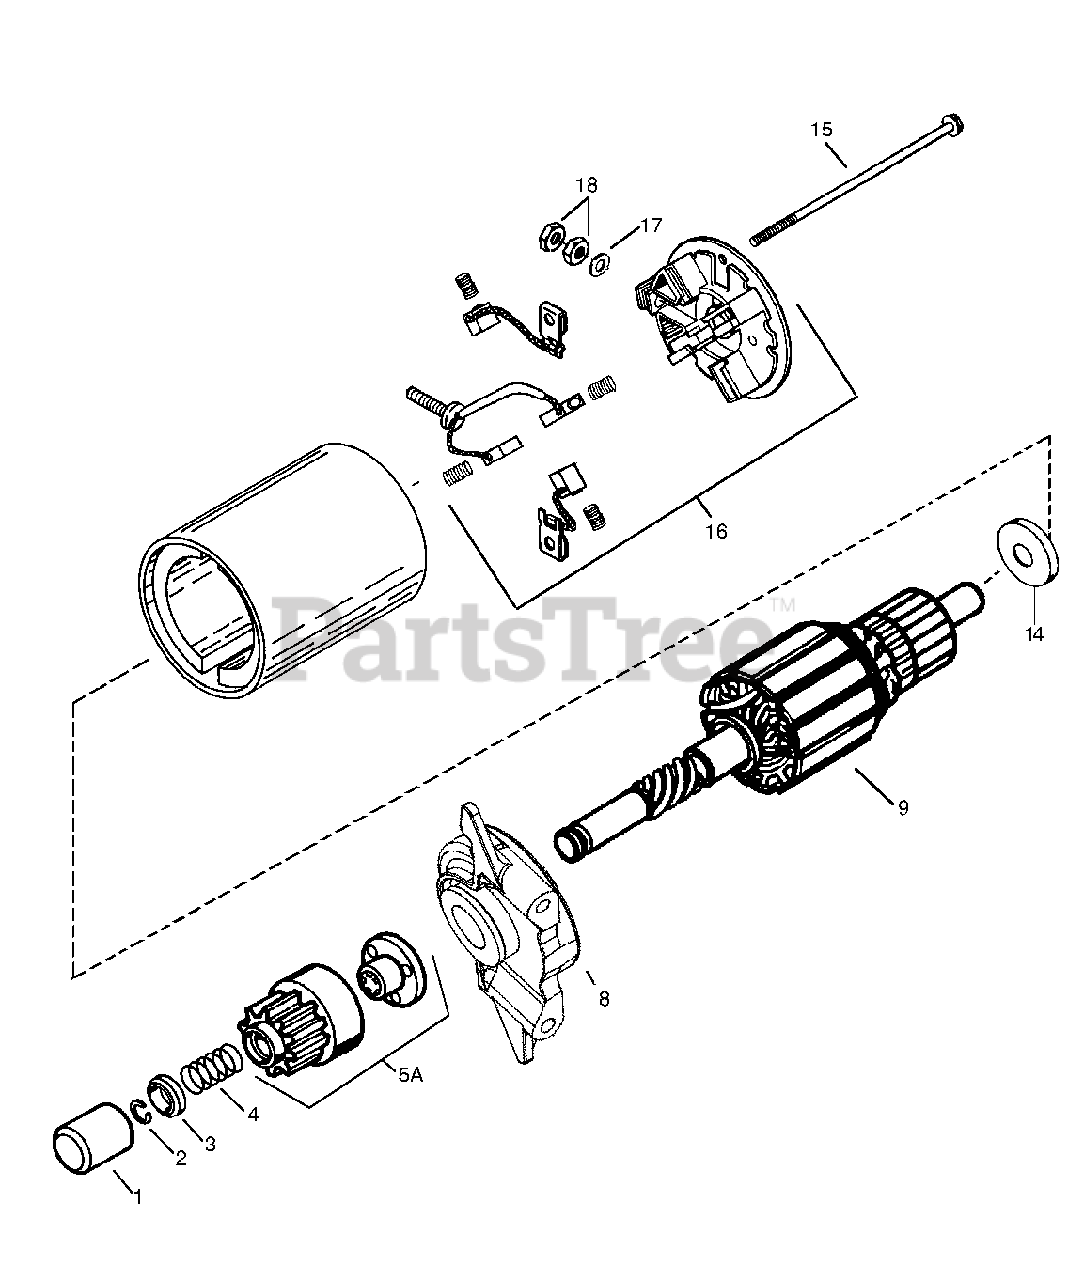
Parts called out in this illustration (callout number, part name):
1	Dust Cover
2	Retainer Ring
3	Spring Retainer
4	Anti-drift Spring
5A	Gear & Nut (Incl. 2)
8	Drive End Cap Assembly
9	Armature
14	Thrust Washer
15	Case Bolt
16	End Cap & Brush Card Ass'y Incl. 14,1 7 & 18
